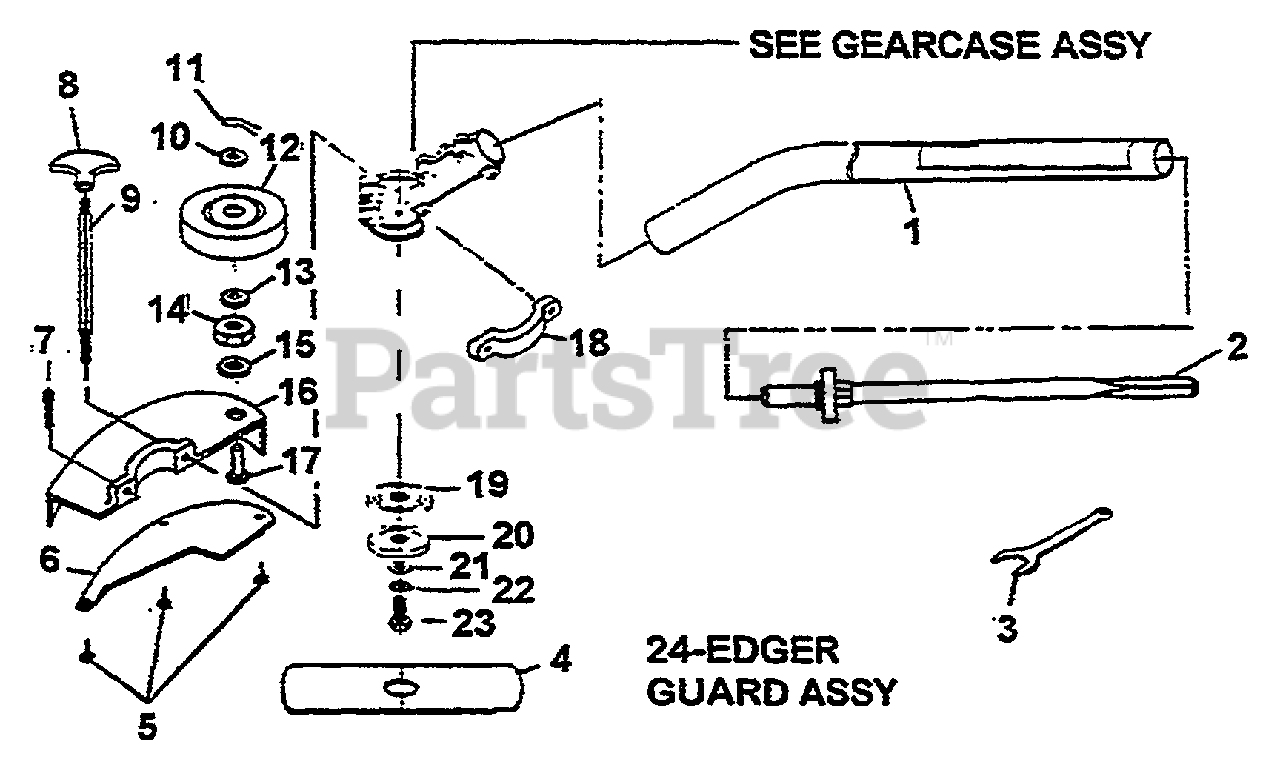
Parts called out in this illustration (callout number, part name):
1	TUBE ASSY
2	FLEX CABLE
3	SPANNER WRENCH
4	EDGER BLADE
5	SCREW
6	EDGER SHIELD
8	KNOB
9	SHAFT & KNOB KIT
11	COTTER PIN
14	NUT
16	EDGER GUARD
17	EDGER AXLE
20	HOLDER B
22	WASHER
23	BOLT
24	EDGER GUARD ASSY
